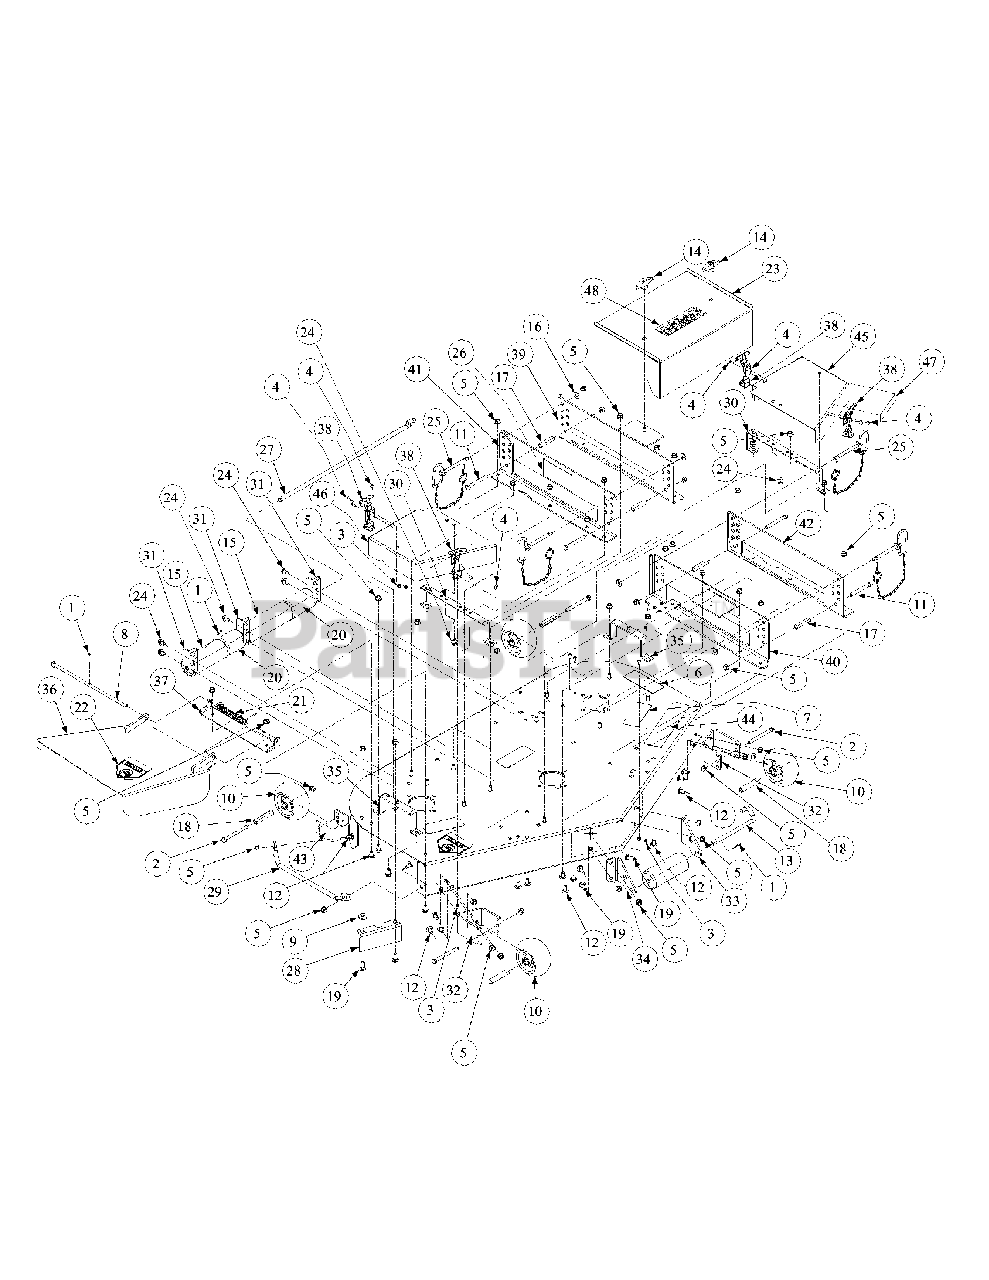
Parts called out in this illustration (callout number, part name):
1	Cotter Pin, .125 Dia. x 1.0
2	Hex Cap Screw, 3/8-16 x 3.75
3	Lock Nut, Nylon Insert, #10-32
4	Phillips Head Screw, #10-32 x 1/2
5	Flange Lock Hex Nut, 3/8-16
6	Decal Rotating Blade
7	Decal Warning Shield Missing
8	Deflector Pin Pivot Assembly
9	Idler Washer
10	Wheel, 5.00 Dia.
11	Hex Cap Screw, 3/8-16 x 3.25 Lg.
12	Carriage Bolt, 3/8-16 x .75 Lg.
13	Roller Pin, 1/2 Dia. x 7.31 Lg.
14	Knob Assembly Wingnut, 5/16-18
15	Front Roller
16	Flat Washer, .385 ID x .870 OD x .092
17	Spacer Stop Deck
18	Wheel Spacer
19	Carriage Bolt, 3/8-16 x 1
20	Grass Catcher Frame Roller
21	Torsion Spring
22	Decal, Danger Hands and Feet
23	Center Belt Cover
24	Hex Index Washer Screw, 3/8-16 x .5
25	Deck Pin 3/8 Dia.
26	Label, Cut Height
27	Roller Pin
28	Chute Bracket
29	Finger Guard
30	Belt Cover Support
31	Roller Mount Bracket
32	Anti-Scalp Wheel Front Mount Bracket
35	Outer Belt Support Cover Assembly
36	Chute Assembly
37	Chute Bracket Weldment
38	T-Handle Latch Draw
39	Right Hand Inner Hanger Assembly
40	Left Hand Inner Hanger Assembly
41	Right Hand Outer Hanger Assembly
42	Left Hand Outer Hanger Assembly
43	48" Deck Weldment
44	Label Commercial Mower
45	Left Hand Belt Cover Weldment
46	Right Hand Belt Cover Weldment
47	Label Mower Deck
48	Label Commercial Mower Deck
